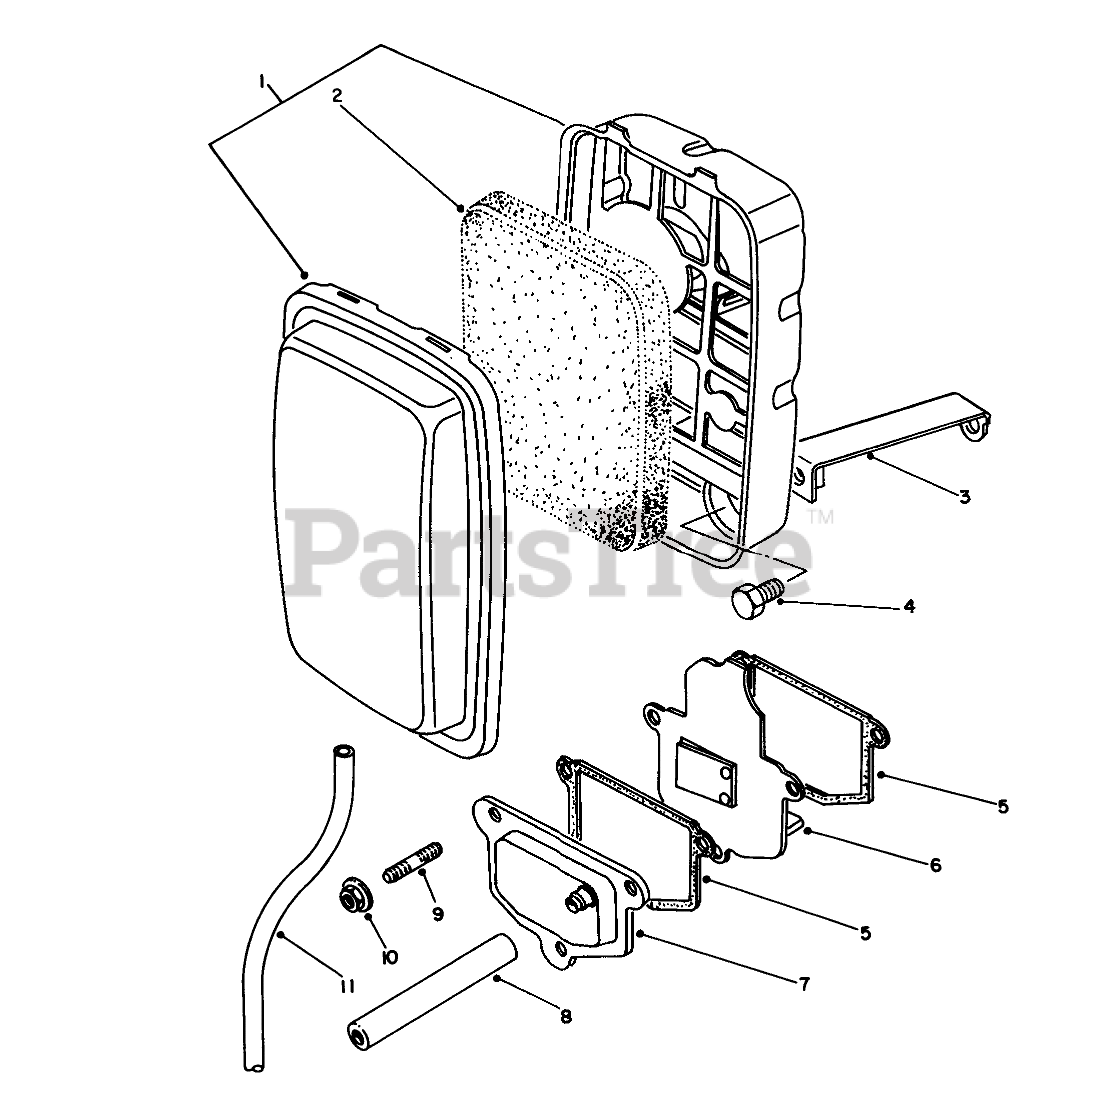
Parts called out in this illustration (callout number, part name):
1	Cleaner Assembly-Air (Incl. Ref. #2)
2	AIR CLEANER FILTER
3	Bracket
5	Gasket
6	Valve
9	Bolt-Stud
